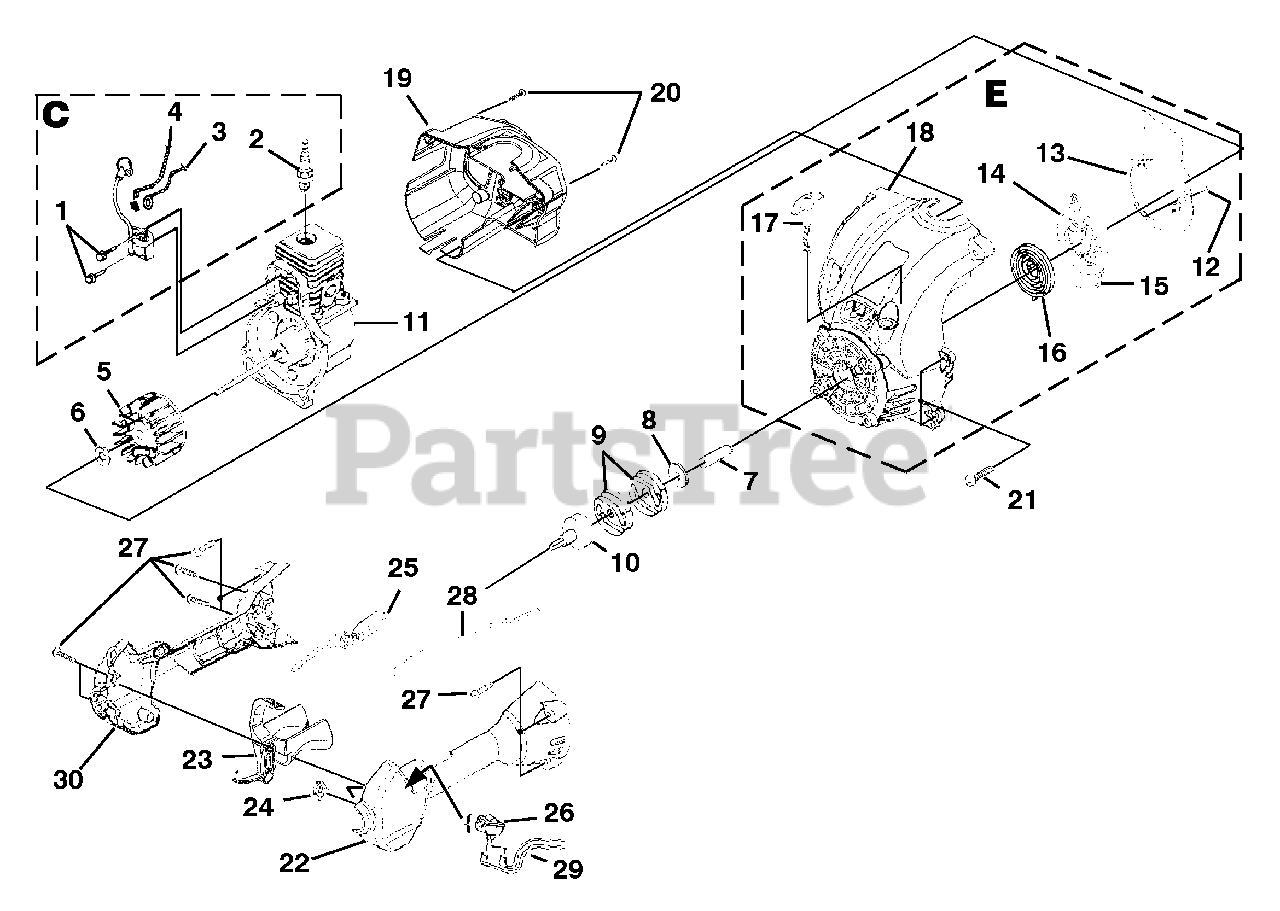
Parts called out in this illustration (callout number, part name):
1	SCREW-Tapite (8-32 X 1)
2	SPARK PLUG
3	LEAD -Electrical
4	LEAD-Electrical
5	ROTOR ASSY.
6	WASHER-Flat
8	WASHER-Flat
10	CONNECTOR AND DRUM
11	SORT BLOCK (See Ei GINe Inter Nal)
12	SCREW-Thread Form (8-16 X 1/2")
13	BAFFLE-Air
14	PULLEY-Starter
15	ROPE Starter (42")
16	SPRING & CONTNER
17	GRIP-Starter (Yel Low)
18	STRATER HSG. ASSSY.
19	HOUSING-Rear
20	SCREW-Plaite (10-14 X 7/8")
21	SCREW-Tapite (10-24 X 3/4")
22	CONTROL HANDLE - LH
23	TRIGGER Throtle
25	THROTTLE INTERLOCK
27	SCREW-Tapite (10-14 X 1")
28	CABLE Throtle
29	LEAD Electrical
30	CONTROL HAN LE - RH
C	IGNITION KT
E	COMPLETE STARTER ASSEMBLY
